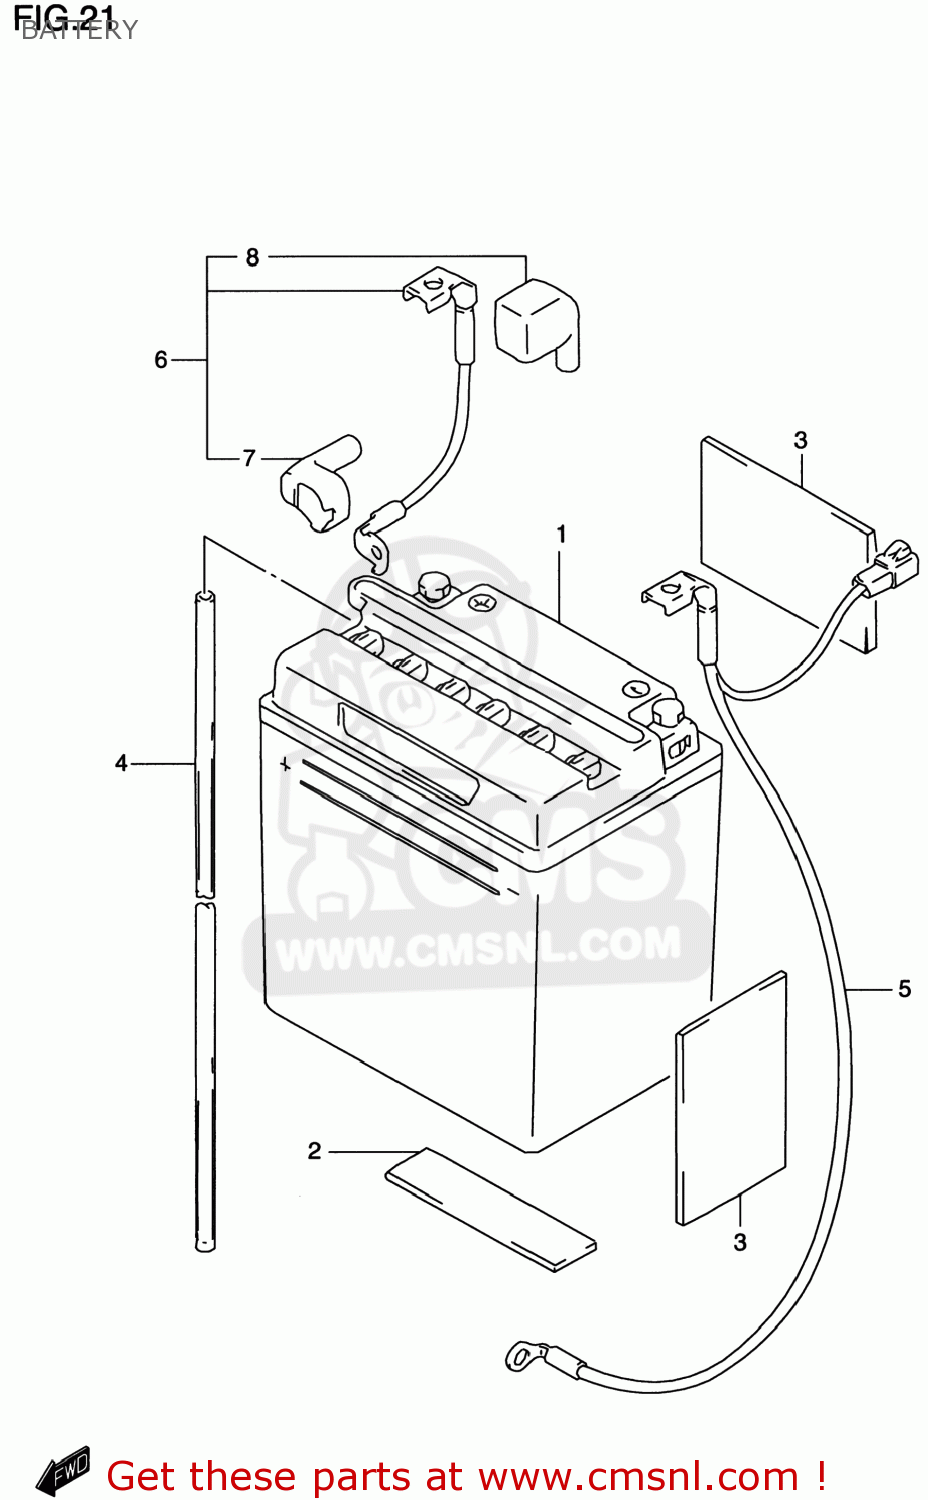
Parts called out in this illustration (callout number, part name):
1	BATTERY ASSY (12V)
2	CUSHION,BATTERY(80X27X3)
3	PROTECTOR(170X95X3.0)
4	HOSE,BATTERY EXHAUST(L:780)
5	WIRE,BATTERY MINUS LEAD
6	WIRE,BATTERY PLUS LEAD
7	CAP,STARTER RELAY TERMINAL
8	CAP,BATTERY PLUS TERMINAL
